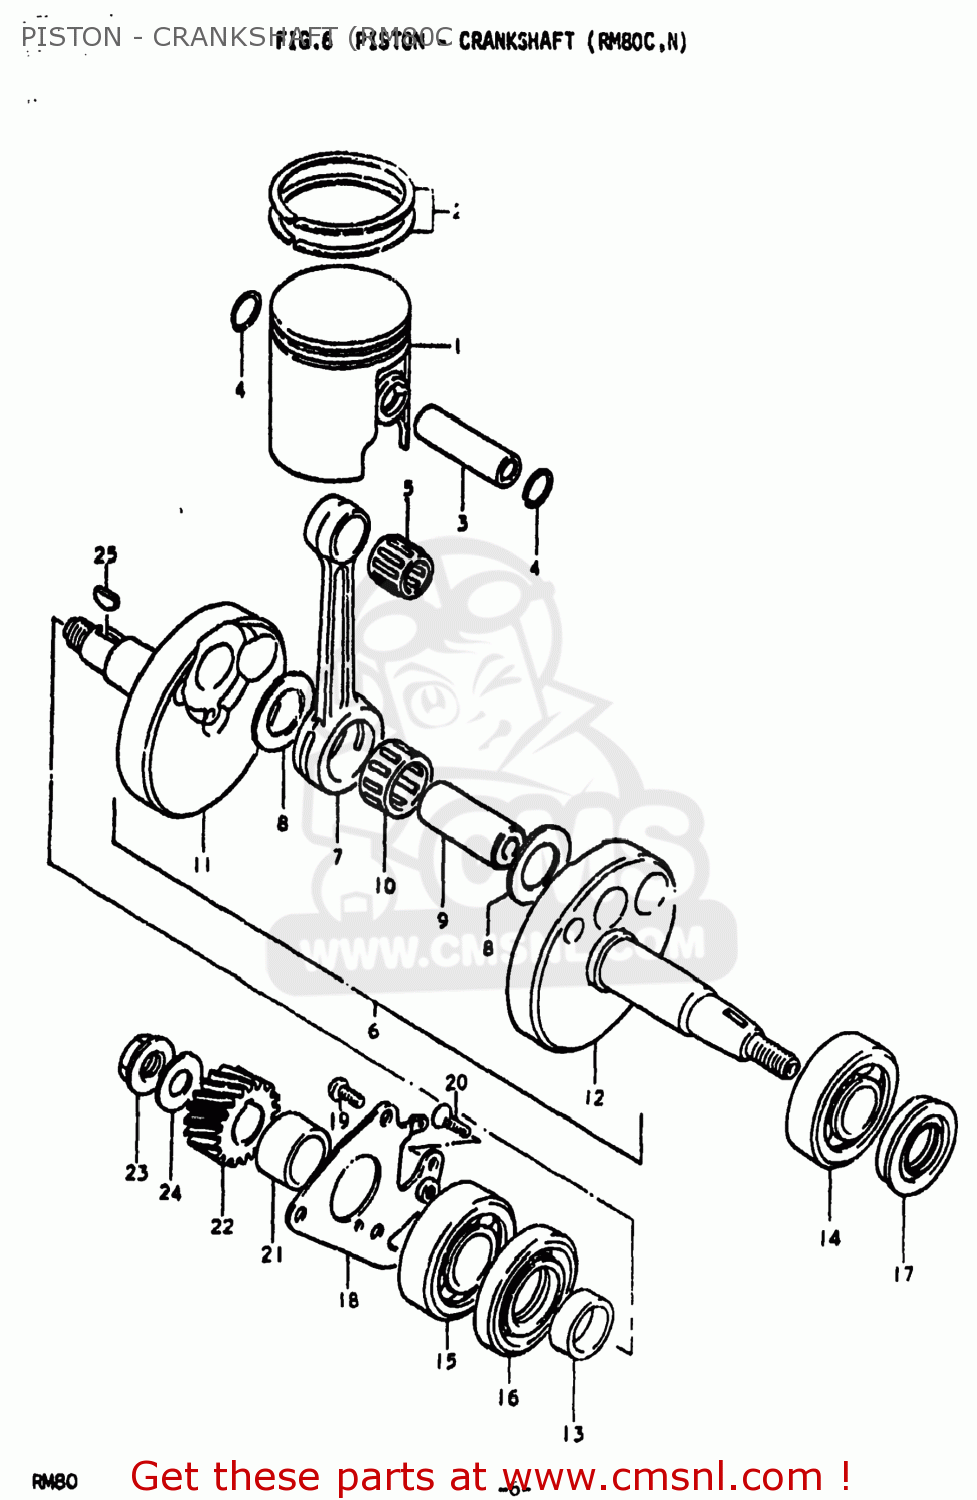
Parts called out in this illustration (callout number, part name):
1	PISTON
2	RING SET,PISTON
3	PIN,PISTON
4	RING,SNAP
5	BEARING
6	CRANKSHAFT ASSEMBLY
7	CONNECTING ROD
8	WASHER
9	PIN,CRANK
10	BEARING
11	CRANKSHAFT
12	CRANKSHAFT,LEFT
13	SPACER(20X26X9)
14	BEARING
15	BEARING
16	OIL SEAL
17	OIL SEAL
18	RETAINER
19	SCREW 6X12
20	SCREW
21	SPACER(20X26X14)
22	GEAR,PRIMARY DRIVE NO.19
23	NUT
24	WASHER
25	KEY
